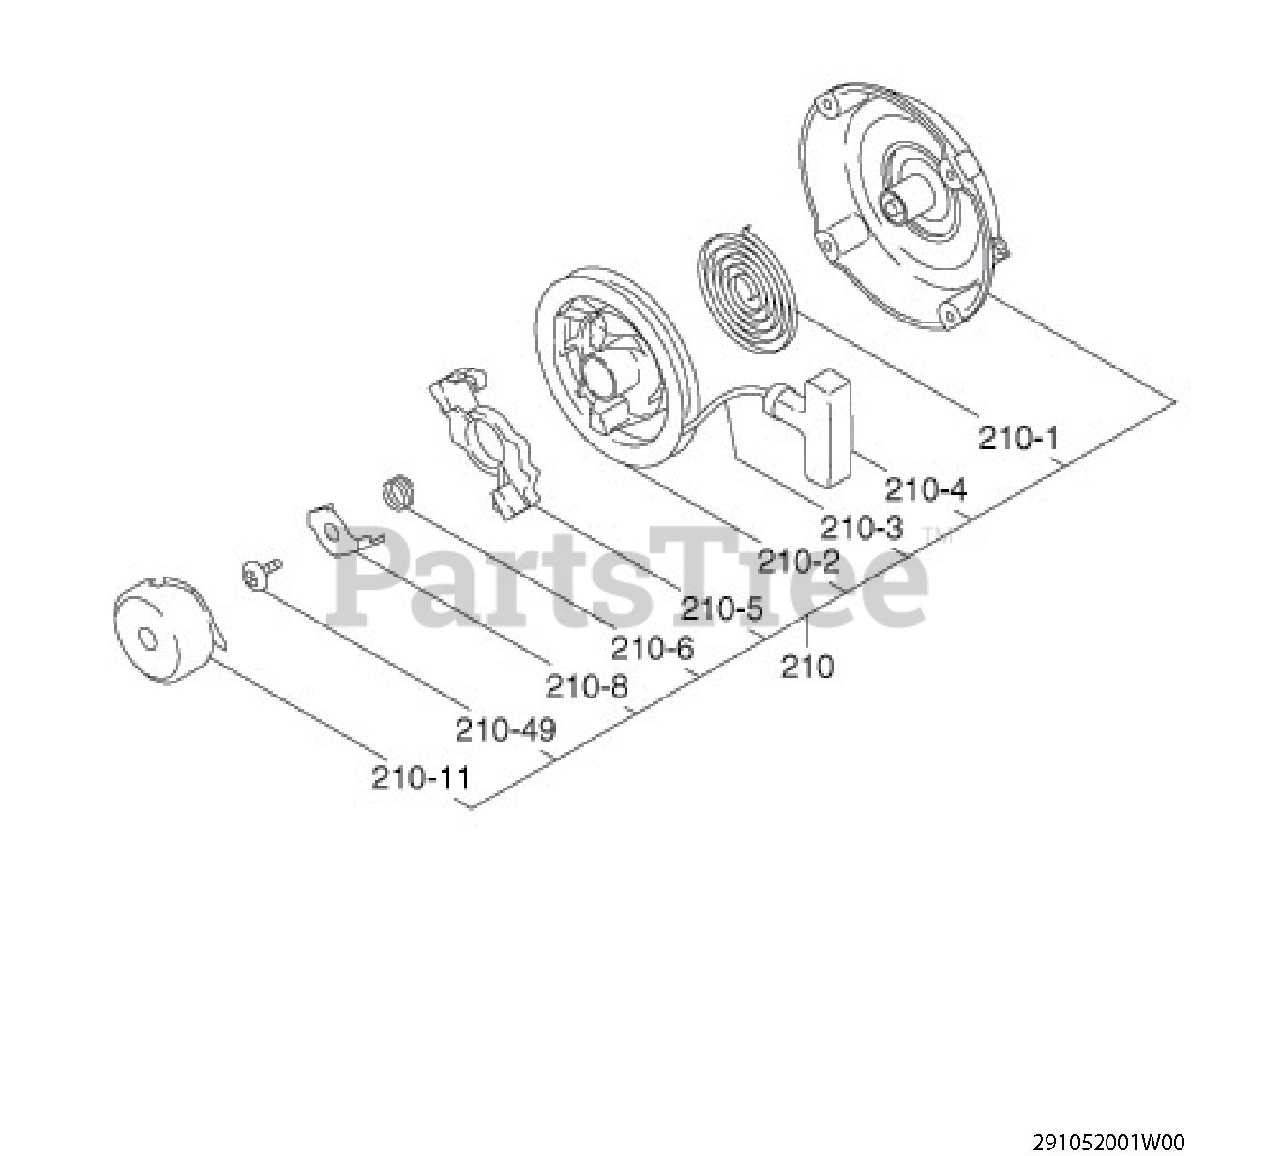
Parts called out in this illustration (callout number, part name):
6	FRICTION SPRING
8	FRICTION PLATE
11	STARTER PULLEY
210	RECOIL STARTER AY
